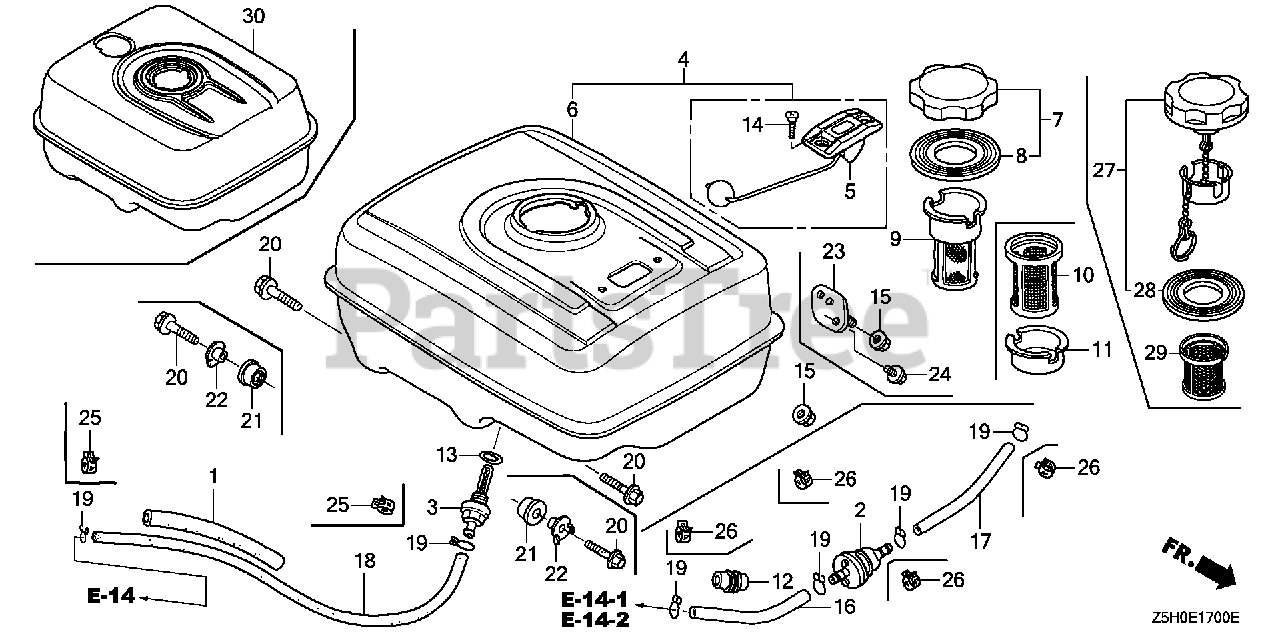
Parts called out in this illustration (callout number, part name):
1	RUBBER, SUPPORTER (107MM)
3	JOINT, FUEL TANK (NOT AVAILABLE)
3	JOINT, FUEL TANK
6	TANK, FUEL *NH31* (MCKINLEY WHITE)
7	CAP, FUEL FILLER (CHROME PLATED)
8	GASKET, FUEL FILLER CAP (39X62X3) (TOUYOUSYA)
9	FILTER, FUEL
13	O-RING (14MM) (ARAI) Use up to Engine SN 2949254.
13	O-RING (14MM) (NOK)
15	NUT, FLANGE (8MM)
18	TUBE, FUEL (4.5X222) (FKM)
18	BULK HOSE, FUEL (4.5X3000) (Honda Code 5137104). (4.5X140)
19	CLIP, TUBE (B8)
20	BOLT, FLANGE (8X25)
25	CLIP, TUBE (D8)
27	CAP, FUEL FILLER
28	GASKET, FUEL FILLER CAP
28	GASKET, FUEL FILLER CAP (39X62X3)
29	FILTER, FUEL (FROM 1204807)
